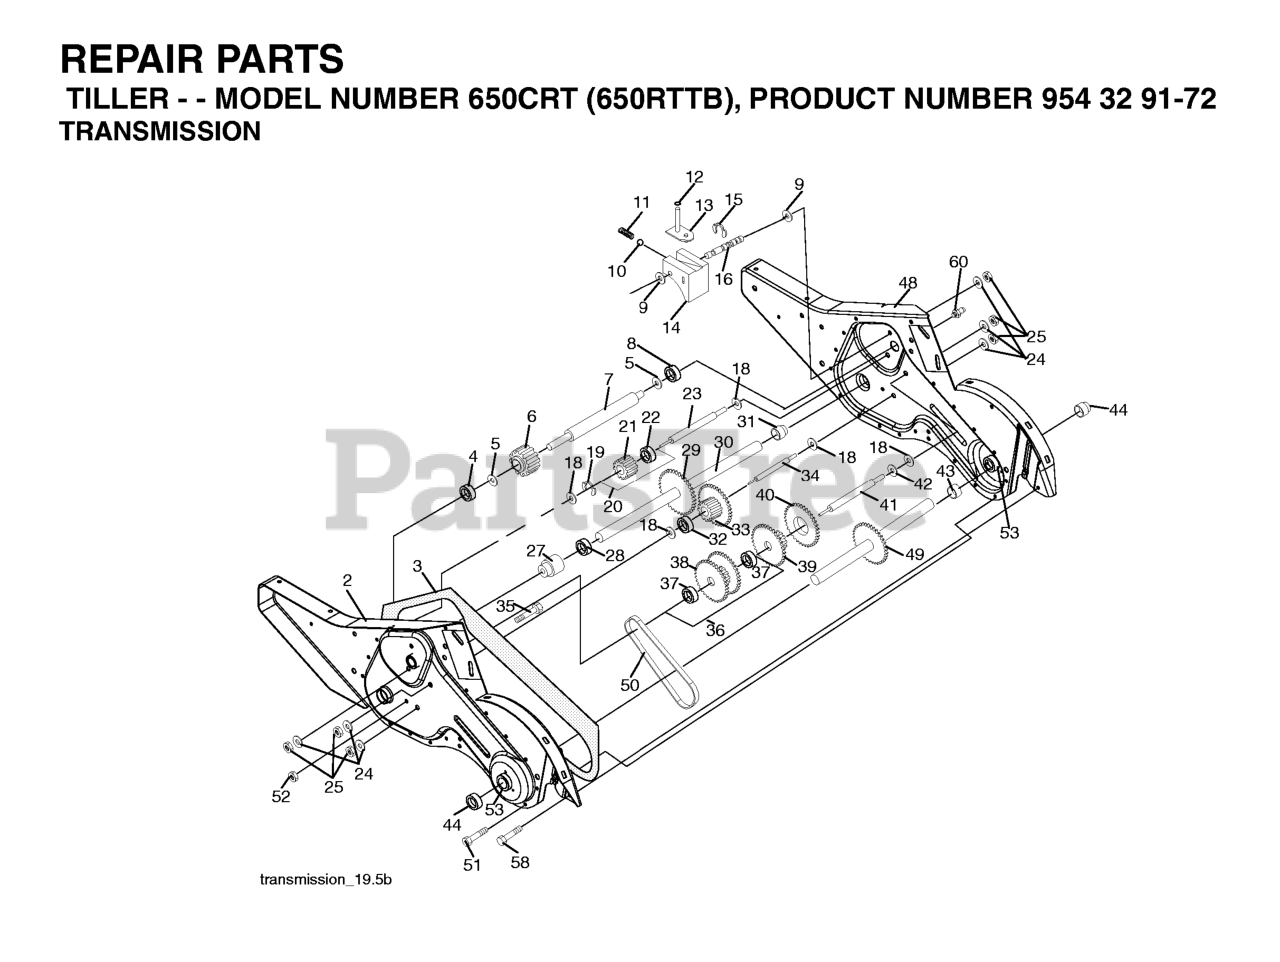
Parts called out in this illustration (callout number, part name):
1	TRANS SERV
2	GEAR CASE
3	GASKET
4	NEEDLE BRNG LT
5	THRUST WASHER
6	GEAR.PINION.INPUT
7	SHAFT.INPUT."D".TILLER
8	BEARING TI
9	WASHER, SEAL (2 2)
10	STEEL BALL KIT
11	SPRING-SHIFT CRT
13	BRACKET ASM.SHIFT.CRT
14	SHIFT FORK TI
16	SHAFT.SHIFTER.TILLER
20	GEAR ASSY CRT
21	GEAR-REV IDLR CRT
22	NEEDLE BEARING TI
24	LOCKWASHER
25	NUT.ASF.HEX.7/16
27	BEARING, SHAFT LH CRT
30	GROUND SHAFT ASS'Y
31	BEARING, SHAFT RH CRT
33	SPRCKT 8 GEAR CRT
34	SHAFT.SECONDARY.REDUCTION.CRT
35	SCRW WHIZ LOK CRT
36	SPROCKET.ASM.W/BEARING.TILLER
37	BEARING
38	SPROCKET, TINE
41	SHAFT.REDUCTION.TILLER
42	BRNG RACE T
44	SEAL ASM, OIL
48	GEARCASE, R.H. W/BEARING
49	TINE SHAFT
50	CHAIN.TILLER
51	SCREW
53	KIT.BEARING.TILLER.
58	BOLT SHOULDER 1/4-20 UNC X.875
60	ZERK M
